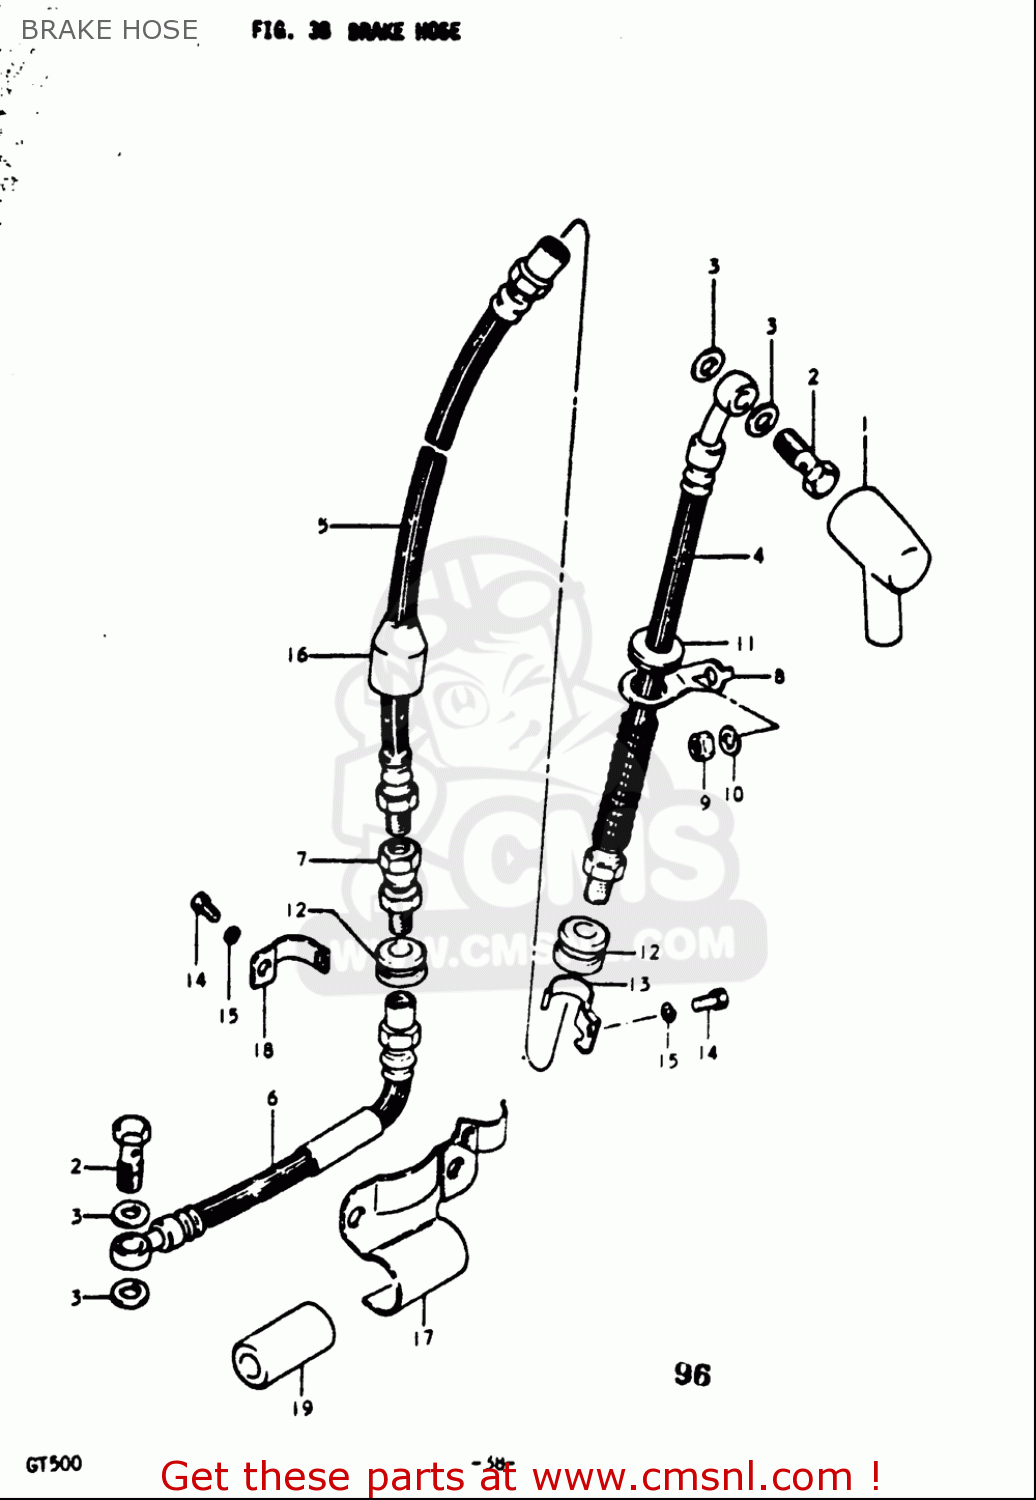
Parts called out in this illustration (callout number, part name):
1	BOOT,MASTER CYLINDER
2	BOLT UNION
3	WASHER(10X15X1.5)
6	HOSE,BRAKE NO.3
9	NUT
10	WASHER,LOCK
11	GROMMET
12	BUSH
14	SCREW(6X12)
15	WASHER,LOCK
19	CUSHION
